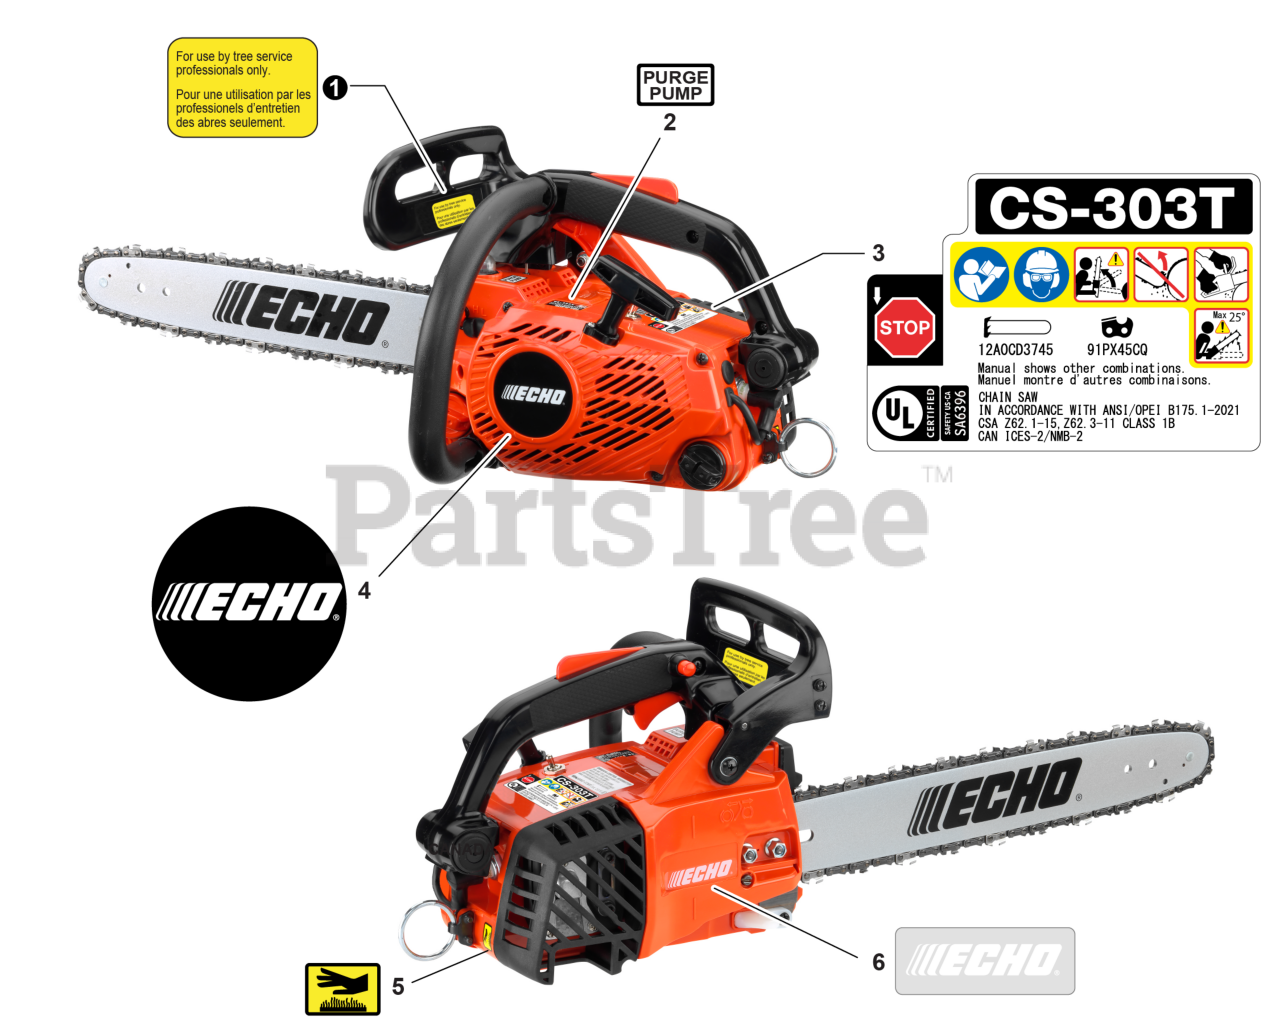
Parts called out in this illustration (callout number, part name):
1	LABEL - CAUTION - PROFESSIONALS ONLY
2	LABEL - PURGE PUMP
3	LABEL - CAUTION
4	LABEL - STARTER - ECHO
5	LABEL - CAUTION - HOT
6	LABEL - ECHO
